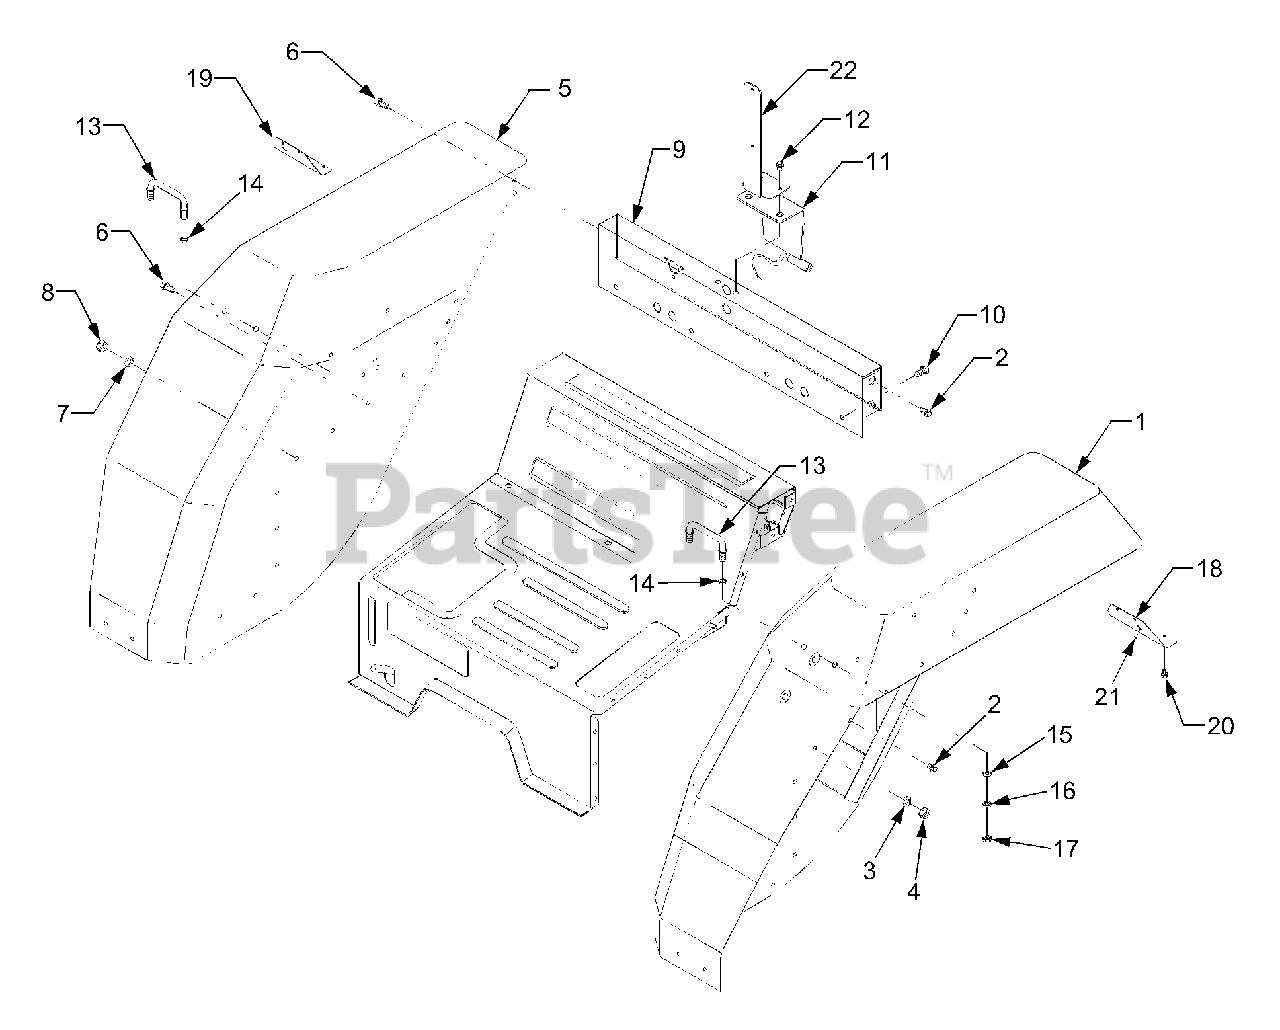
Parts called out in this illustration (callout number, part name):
1	Fender (LH) Ass'y
3	Washer, Spring
5	Fender (RH) Ass'y
7	Washer, Spring
9	Support, Fender
11	Hook, Top Link
14	Cushion
15	Washer, Plain
16	Washer, Spring
